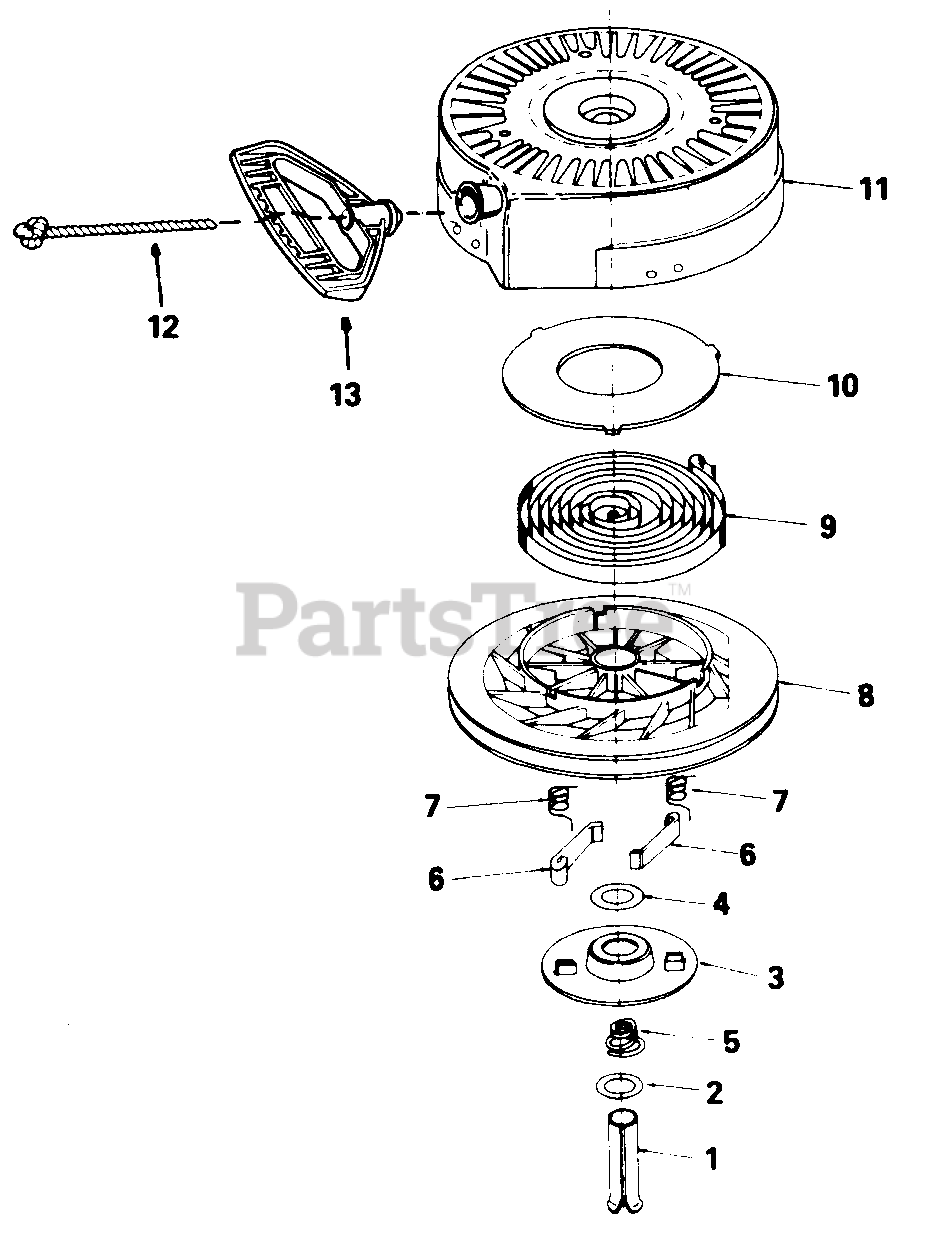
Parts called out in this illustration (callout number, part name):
1	Pin, Spring
5	Spring, Brake
6	Dog, Starter
7	Spring, Dog
8	Pulley
9	Spring, Rewind
10	Cover, Spring
11	Housing Ass'y., Starter
12	Rope, Starter
13	Handle, Mitten Grip
